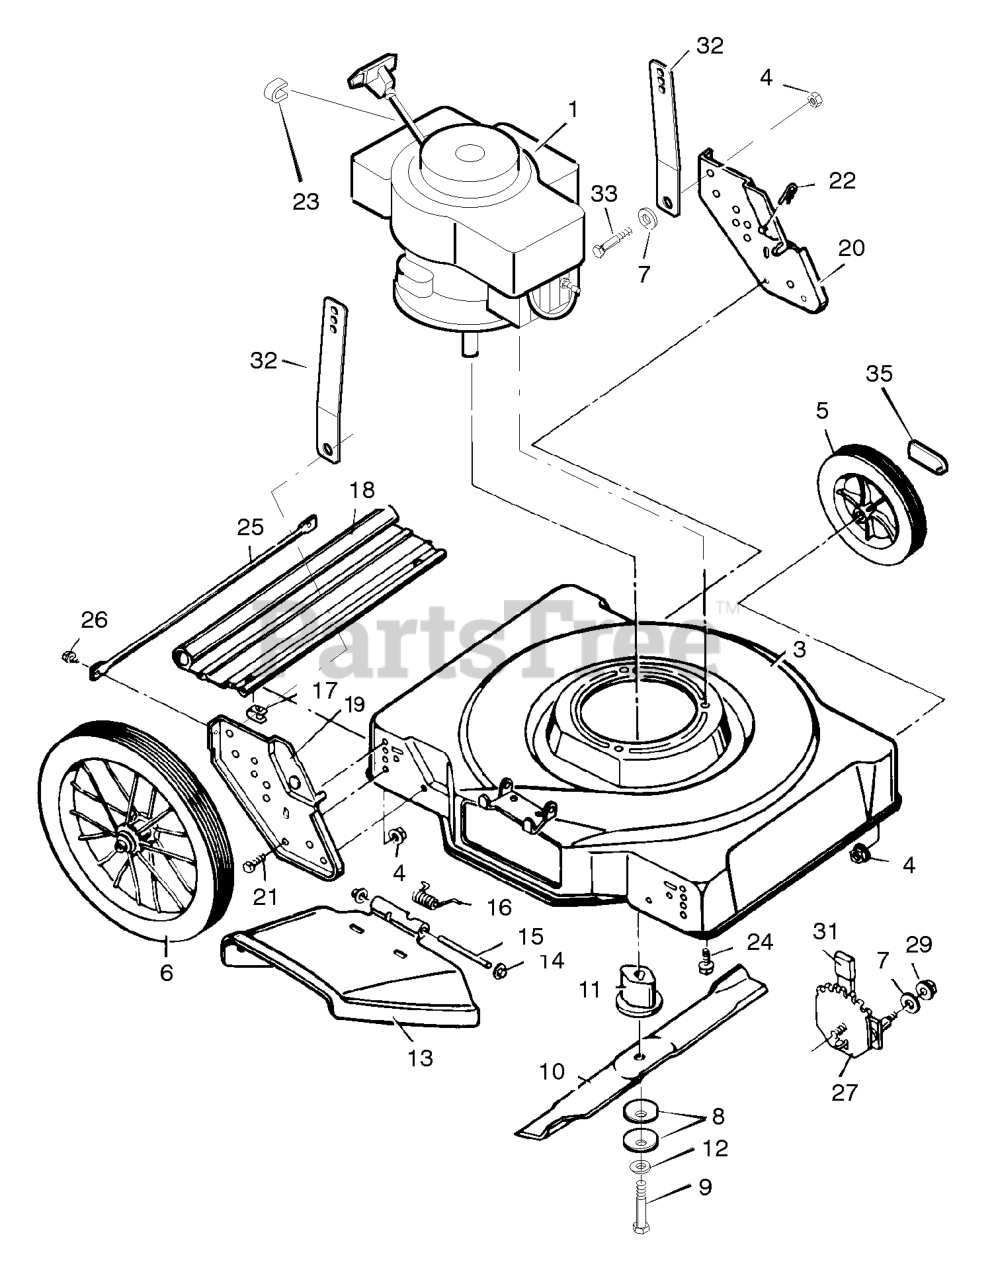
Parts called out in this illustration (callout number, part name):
1	Engine *
3	Housing
4	Nut, Hex
5	Wheel and Tire, Front *
6	Wheel and Tire, Rear *
8	Washer, Blade
9	Bolt, Hex
10	Blade - Standard
11	Blade Adapter
13	Deflector, Chute
14	Push On Cap
15	Pin, Pivot
17	Retainer
18	Deflector, Rear
19	Bracket, Right Wheel
20	Bracket, Left Wheel
21	Bolt, Hex
22	Pin, Hair
23	Stop, Rope
24	Bolt, Engine
27	Height Adjuster, Front
29	Locknut
32	Support, Handle
33	Bolt, Shoulder
35	Hub Cap
